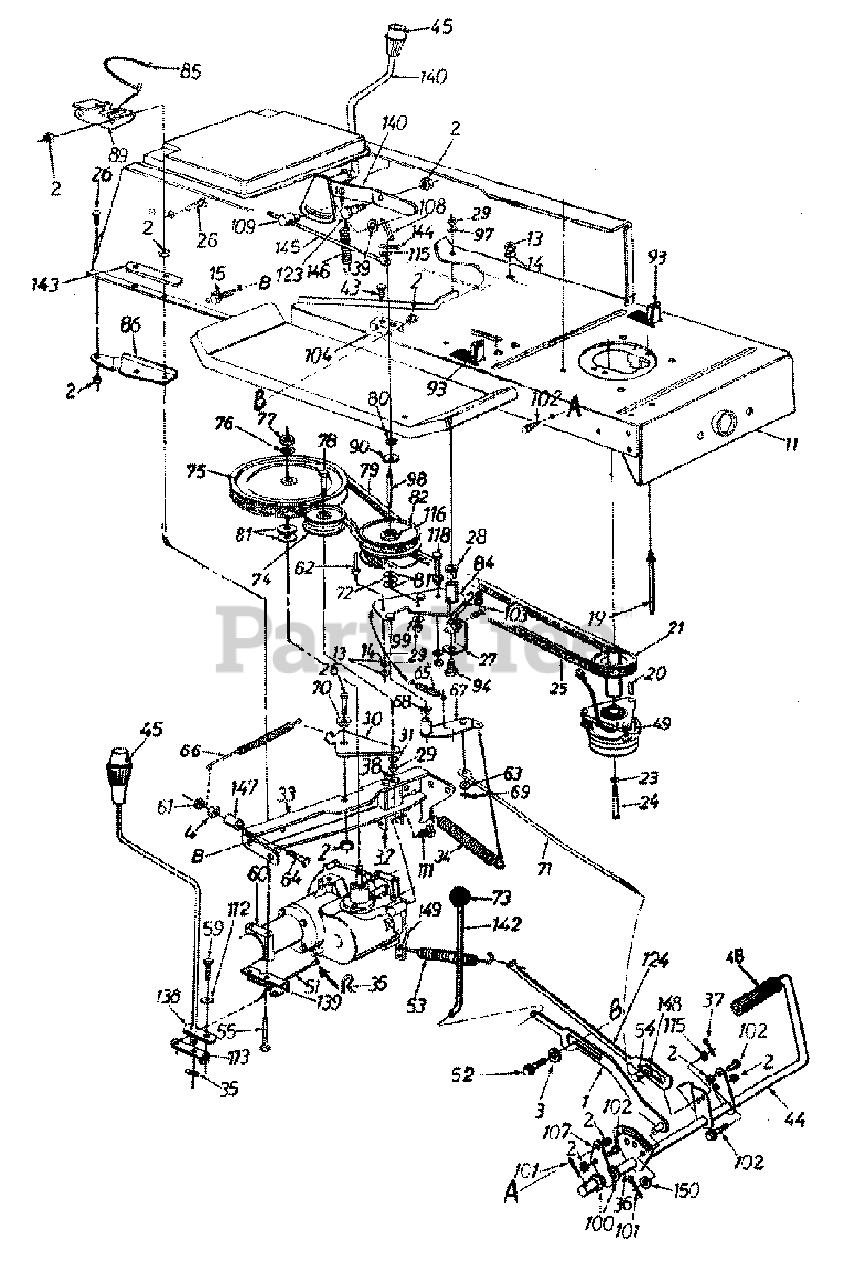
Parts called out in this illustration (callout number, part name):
1	Parking Brake Lockout Brkt. Ass'y.
2	Hex Sems Nut 5/16-18 Thd.
3	Fl-Wash. .442" I.D. x 1.38" O.D.
4	Hex Nut 5/16-24 Thd.
11	Lower Frame Ass'y.
13	Hex Nut 1/4-20 Thd.
14	L-Wash. 1/4" I.D.
19	Belt Guard Pin
20	Sq. Key 1/4" x 1/4" x 1.5"
21	Engine Pulley
23	L-Wash. 7/16" I.D.
24	Hex Bolt 7/16-20 x 2.5" Lg.
25	Variable Speed Belt
26	Hex Bolt 5/16-18 x .75" Lg.
27	Bearing Shaft Bracket Ass'y.
28	Flanged Nyliner Brg. .63" I.D. x .6" Lg.
29	Hex Nut 3/8-24 Thd.
30	Idler Bracket
31	L-Wash. 3/8" I.D.
35	Inter. Cotter Pin
36	Spacer .63" I.D.
37	Cotter Pin 1/8" Dia. x 1.0" Lg.
38	Self-Tap Scr. 5/16-18 x .5" Lg.
39	FL-Wash. .51" I.D. x .75"
43	Hex Wash. Hd. S-Tap Scr. 1/4-20 x .50" Lg.
48	Foot Pad
49	Electric Clutch
51	Shift Lever Rod
52	Shld. Bolt .437"
53	Ext. Spring 3.6"
54	Ferrule
55	Hex Bolt 5/16-18 x 3.25"
59	Hex Bolt 1/4-28 x .62" Lg.
60	Transaxle Complete
61	Hex L-Nut 1/4-20 Thd.
62	Belt Guard Pin 1/4-20 Thd.
63	Fl-Wash. .34" I.D. x .68" O.D.
64	Hex Wash. TT-Tap Scr. 1/4-20 x 1.75"
65	Ext. Spring 2.59" Lg.
66	Ext. Spring .5" O.D. x 4.35"
68	Flanged Bearing
69	Cotter Pin 3/32" Dia.
70	Shoulder Spacer .27" Lg.
71	Speed Control Link
72	Truss Bearing .56 Dia. x 1.25"
74	Fl-Idler Pulley 3.25" x .75"
76	L-Wash. 1/2" I.D.
77	Hex Jam Nut 1/2-20 Thd.
78	Hex Bolt 3/8-24 x 1.75" Lg.
79	Variable Speed Belt
80	Snap Ring .56" Dia.
81	Fl-Wash. .56" I.D. x 1.0" O.D.
82	Variable Speed Pulley Ass'y. 5" O.D.
90	Teflon Washer .565" I.D.
93	Safety Switch (Clutch)
94	Shld. Bolt 3/8-24 x 3.12" Lg.
97	Bell-Wash. .38" I.D. x .88"
99	Bell-Wash. .39" I.D. x 1.12"
100	Fl-Wash. .64" I.D. x .94"
101	Cotter Pin 3/32" Dia. x 1" Lg.
102	Hex Wash. Hd. Scr. 5/16-18 x .62" Lg.
107	Pedal Bracket
109	Ferrule
111	Hex Wash. Tap Scr.
112	Bell-Wash. .265" I.D. x .75"
113	Shift Lever Link Ass'y.
115	Fl-Wash. .385" I.D. x .62"
116	Needle Bearings
118	Hex Bolt 1/4-20 x 3.5" Lg.
123	Shld. Bolt .437" Dia. x .162"
124	Brake Rod Ass'y.
138	Shift Lever Ass'y.
139	Shift Lever Support Brkt.
140	Speed Selector Lever Ass'y.
142	Brake Lockout Rod
144	Cotter Pin 1/8" x 3/4" Lg.
145	Speed Selector Rod
146	Ext. Spring 3.97" Lg.
147	Spacer .326" I.D. x .47"
148	Fl-Wash. 5/8" I.D. x 1.25"
149	Actuating Arm
150	Fl-Wash. .385" I.D. x .62" O.D.
